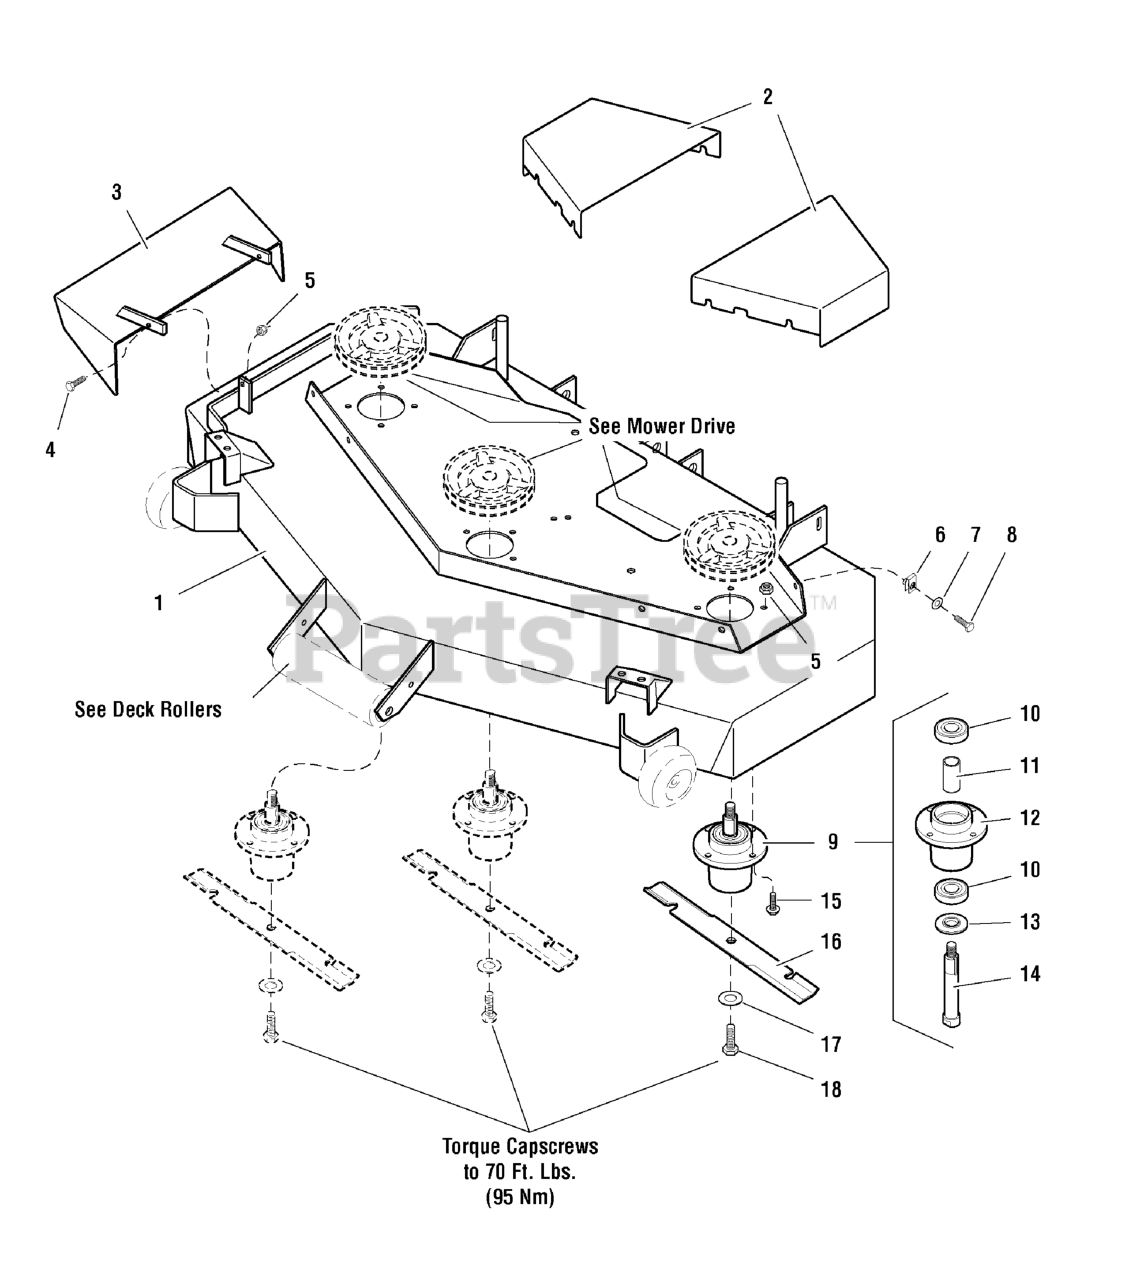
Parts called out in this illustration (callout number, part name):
1	DECK SHELL W/DECALS, 48"
1	DECK SHELL W/DECALS, 52"
2	MOWER HOUSING GUARD
3	DISCHARGE CHUTE
4	BOLT, 5/16-18 X 1 GD5 YZ
5	NUT, 5/16-18 Hex Nylon Lock
6	BODY CLIP, 5/16-18-7GA MATERIAL
7	WASHER, 5/16" SAE
8	BOLT, 5/16-18 X 3/4 GD5
9	* SPINDLE ASSEMBLY, Complete
15	BOLT, Flange Head, 5/16-18 x 1-1/4
16	MOWER BLADE, 16-1/4"
16	MOWER BLADE, 18"
17	WASHER, 5/8" USS
18	BOLT, 5/8-11 X 1-3/4 GD8
